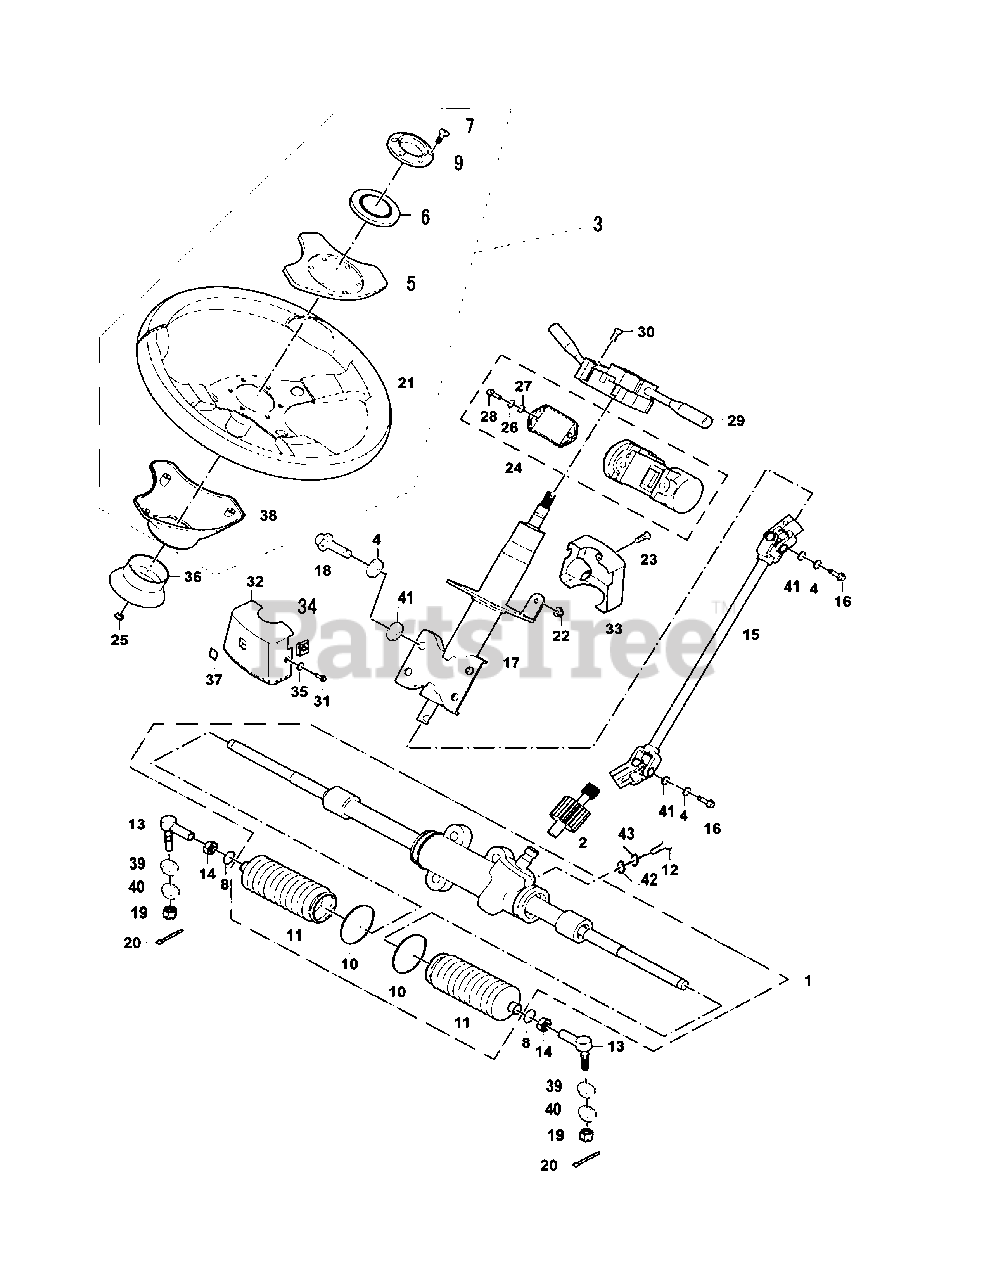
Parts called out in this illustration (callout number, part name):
1	Steering Mechanism Comp
3	Steering Wheel Comp
4	Spring Washer -8
5	Upper Cover, Steering Wheel
6	Middle Cover, Steering Wheel
7	Socket Hexagon Screw M6x16
8	Pipe Clamp 15
9	Decoration Cover, Steering Wheel
10	Clip
11	Rubber Dust Cover
12	Hexagon Flange BoltM10x1.25x35
13	Steering Wheel Ball Joint
15	Steering Drive Axle
16	Hexagon Flange Bolt M8x25
17	Steering Column
18	Hexagon Flange Bolt M8x25
20	Cotter pin 2x32
21	Steering Wheel Body
22	Hexagon flange nut M5
23	Cross Large Plate Head Screw M5x12
24	Ignition switch
25	Hexagon Flange Nut M12x1.25
27	Tapping Clamp F4.2
28	Screw M5x16
29	Combination Switch
30	Cross Large Plate Head Screw M5x16
32	Upper Cover,Ignition Switch
33	Lower Cover,Ignition Switch
34	Tapping Clamp F4.2
35	Washer 5x15x1.2
36	Decoration Cover, Steering Column
37	Rubber Cushion ,Ignition Switch Cover
38	Lower Cover, Steering Wheel
39	Cushion 15x28x2
40	Spring Washer -14
41	Cushion 8.4x16x1.6
42	Washer10x20x2
43	Spring washer -10
